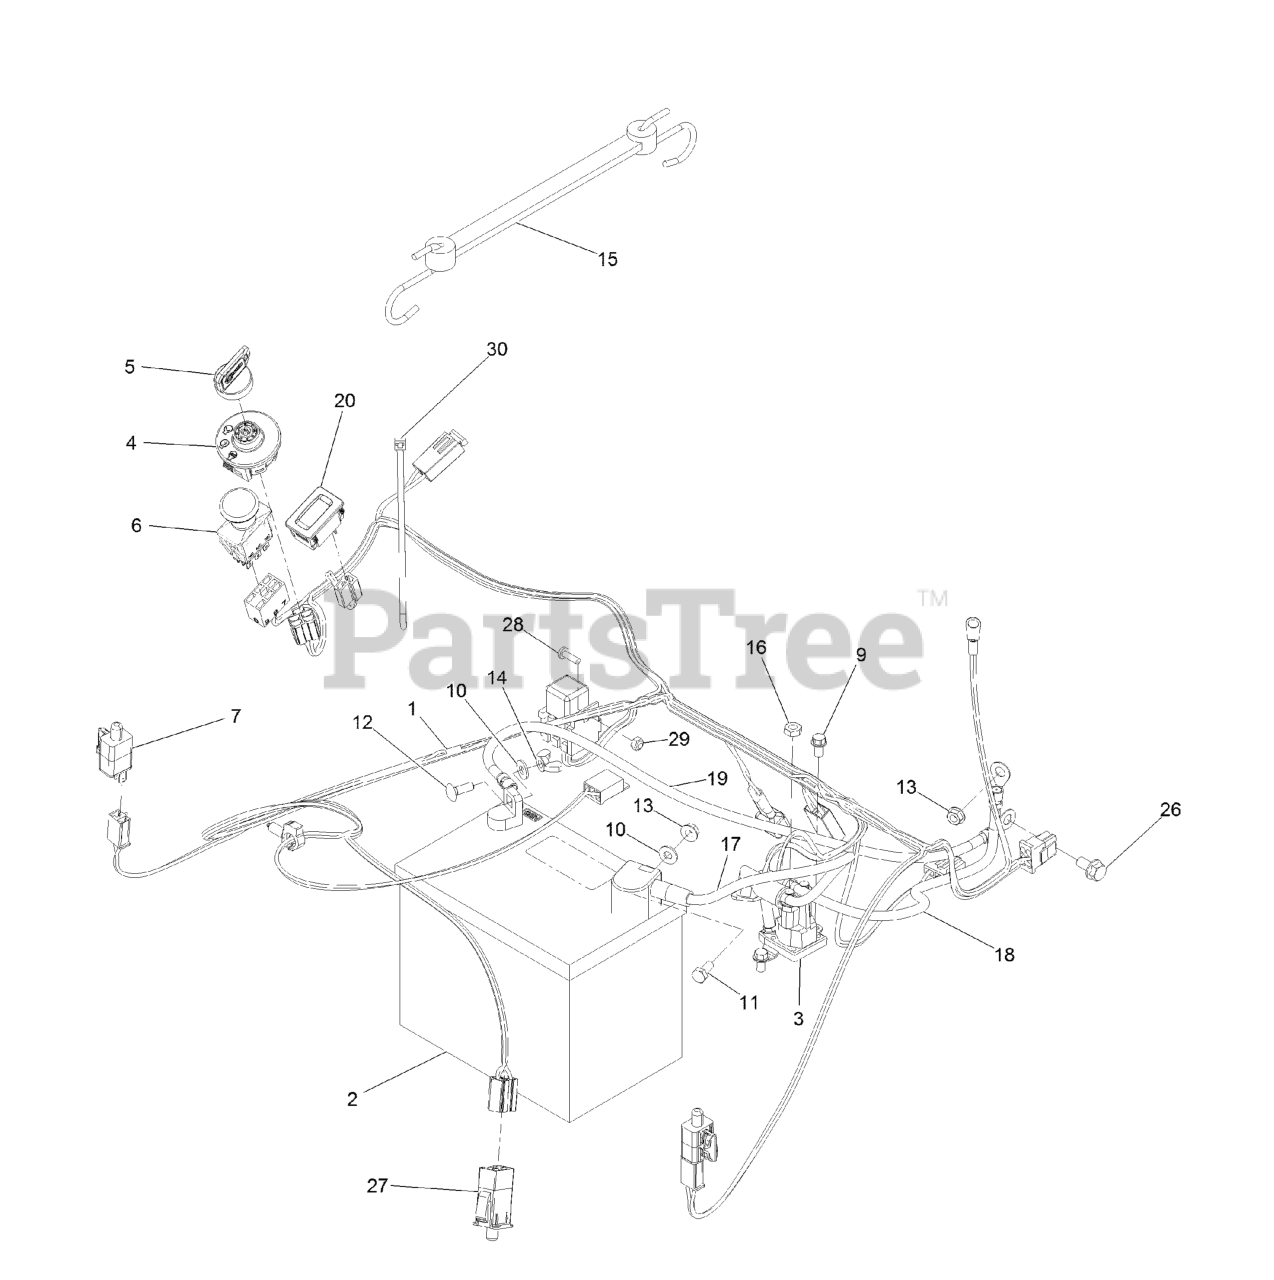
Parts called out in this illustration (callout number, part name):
1	HARNESS-WIRE
2	BATTERY
3	SOLENOID
4	SWITCH-IGNITION
5	KEY-IGNITION
6	SWITCH-PTO
9	SCREW-HWH
10	WASHER-FLAT
11	SCREW-HH
12	BOLT-CARR
14	NUT-WING
15	HOLDDOWN-BATTERY
16	NUT-JAM
17	CABLE-BATTERY, RED
18	CABLE-BATTERY, RED
19	CABLE-BATTERY, BLACK
20	HOURMETER
26	SCREW-HHF
27	SWITCH-DELTA
28	SCREW-PPH
29	NUT-LOCK, NI
30	TIE-CABLE
